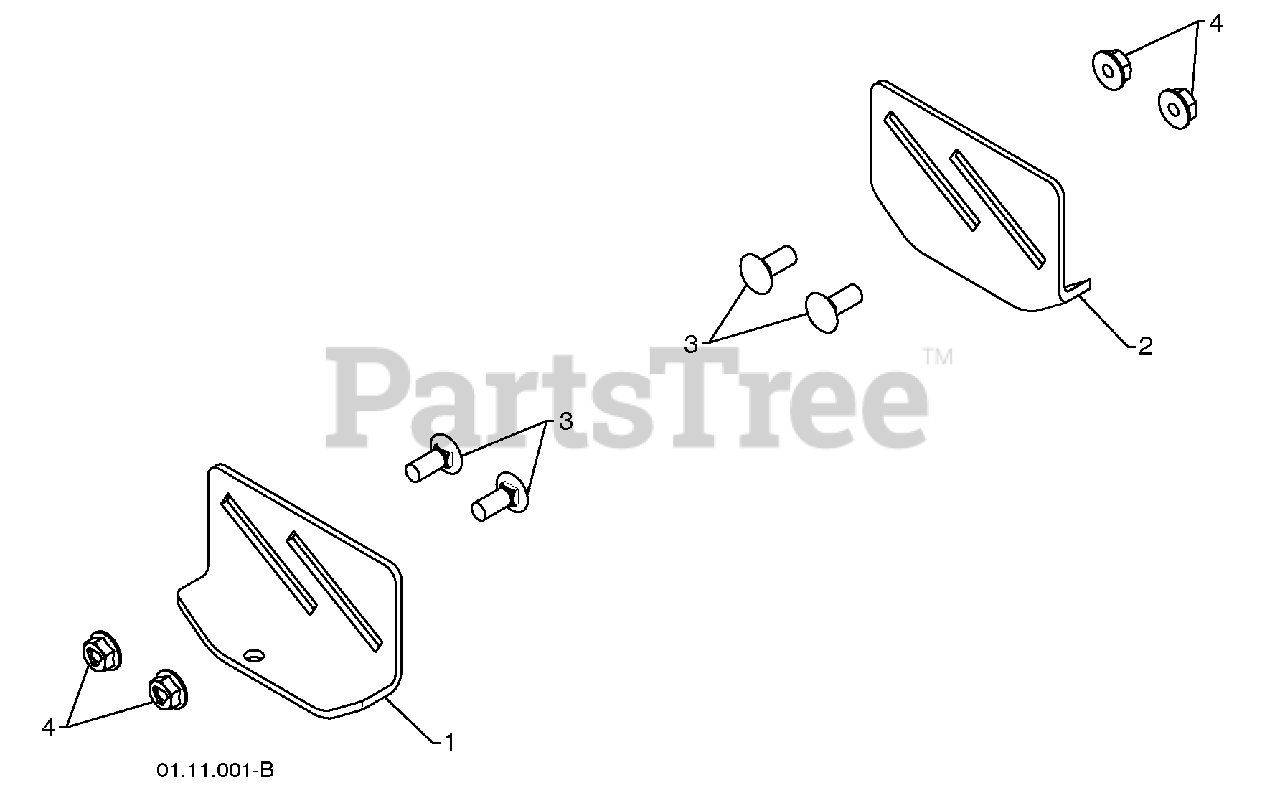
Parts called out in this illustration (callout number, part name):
1	SKID PLATE LH
2	SKID PLATE RH
3	CARRIAGE BOLT 5/16-18 X .75
4	NUT 5/16-18
